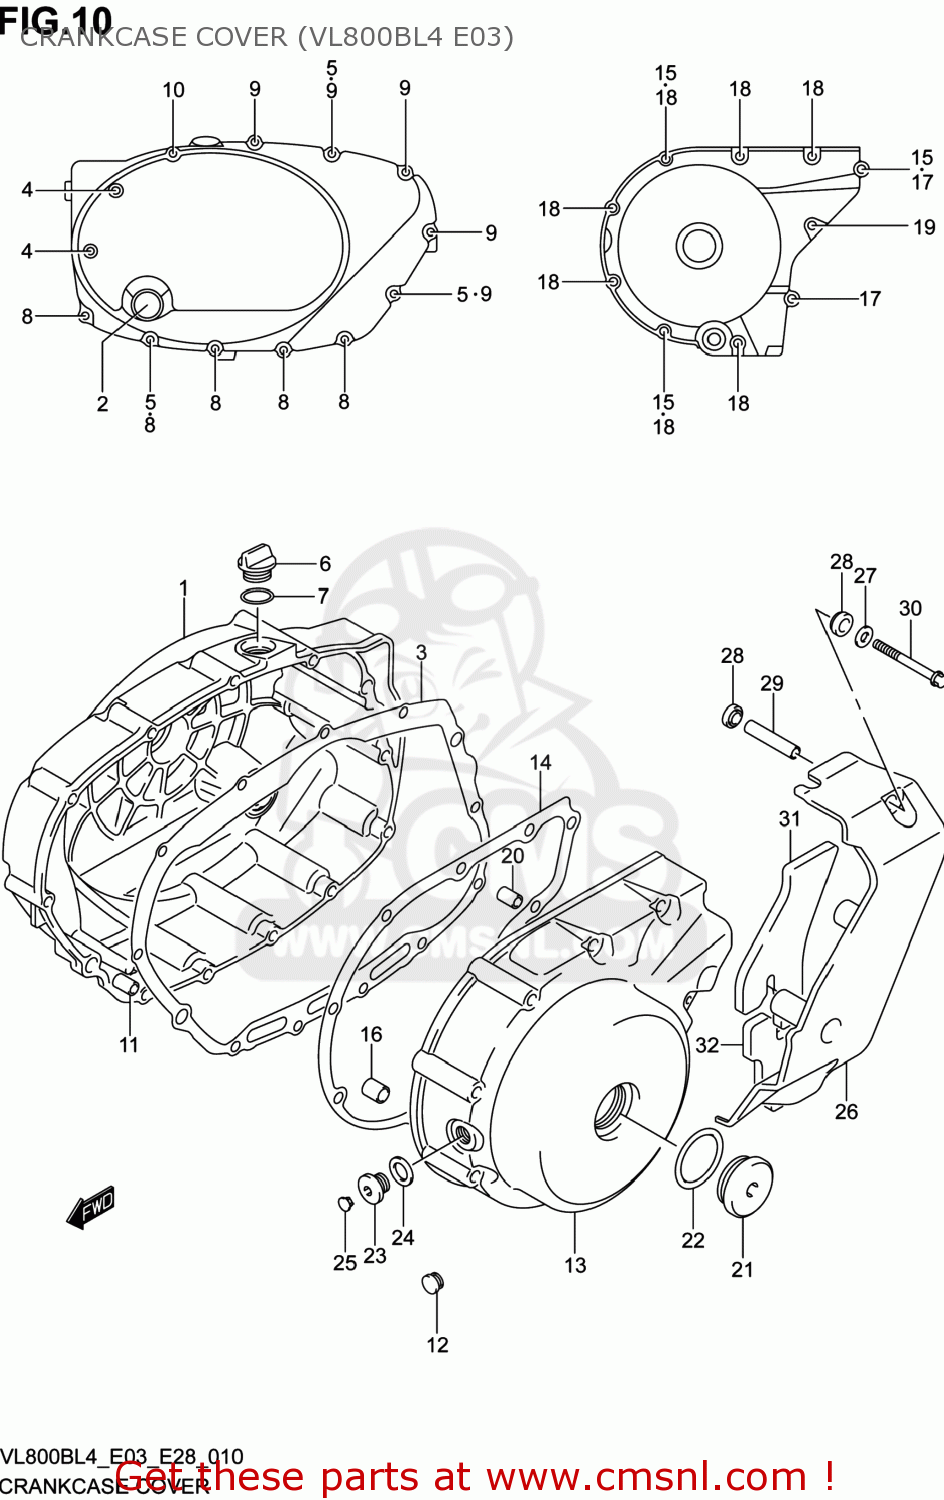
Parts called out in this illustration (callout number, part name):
1	COVER,CLUTCH
2	LENS,OIL LEVEL CHECK
3	GASKET,CLUTCH COVER (NAS)
4	BOLT(6X105)
5	GASKET(5.8X13X1.2) (NAS)
6	PLUG,ENGINE OIL FILLER
7	O RING(D:3.1,ID:16.8)
8	BOLT(6X30)
9	BOLT(6X50)
10	BOLT(6X85)
11	PIN
12	CAP(OD:12)
13	COVER,GENERATOR
14	GASKET,GENERATOR COVER (NAS)
15	GASKET(5.8X13X1.2) (NAS)
16	PIN(8.4X11X20)
17	BOLT(6X40)
18	BOLT(6X55)
19	BOLT(6X85)
20	PIN
21	Chrome Crankshaft Plug
22	O RING(D:3.1,ID:32.7)
23	PLUG,14X12
24	GASKET(13.8X18.8X4.8) (NAS)
25	CAP(OD:12)
26	COVER,SECONDARY DRIVE UNIT
27	WASHER(6.5X14X1.6)
28	WASHER(8.7X16X5)
29	SPACER(6.5X9X41.3)
30	BOLT(6X55)
31	CUSHION,SEC DR UNIT COVER NO.1
32	CUSHION,SEC DR UNIT COVER NO.2
